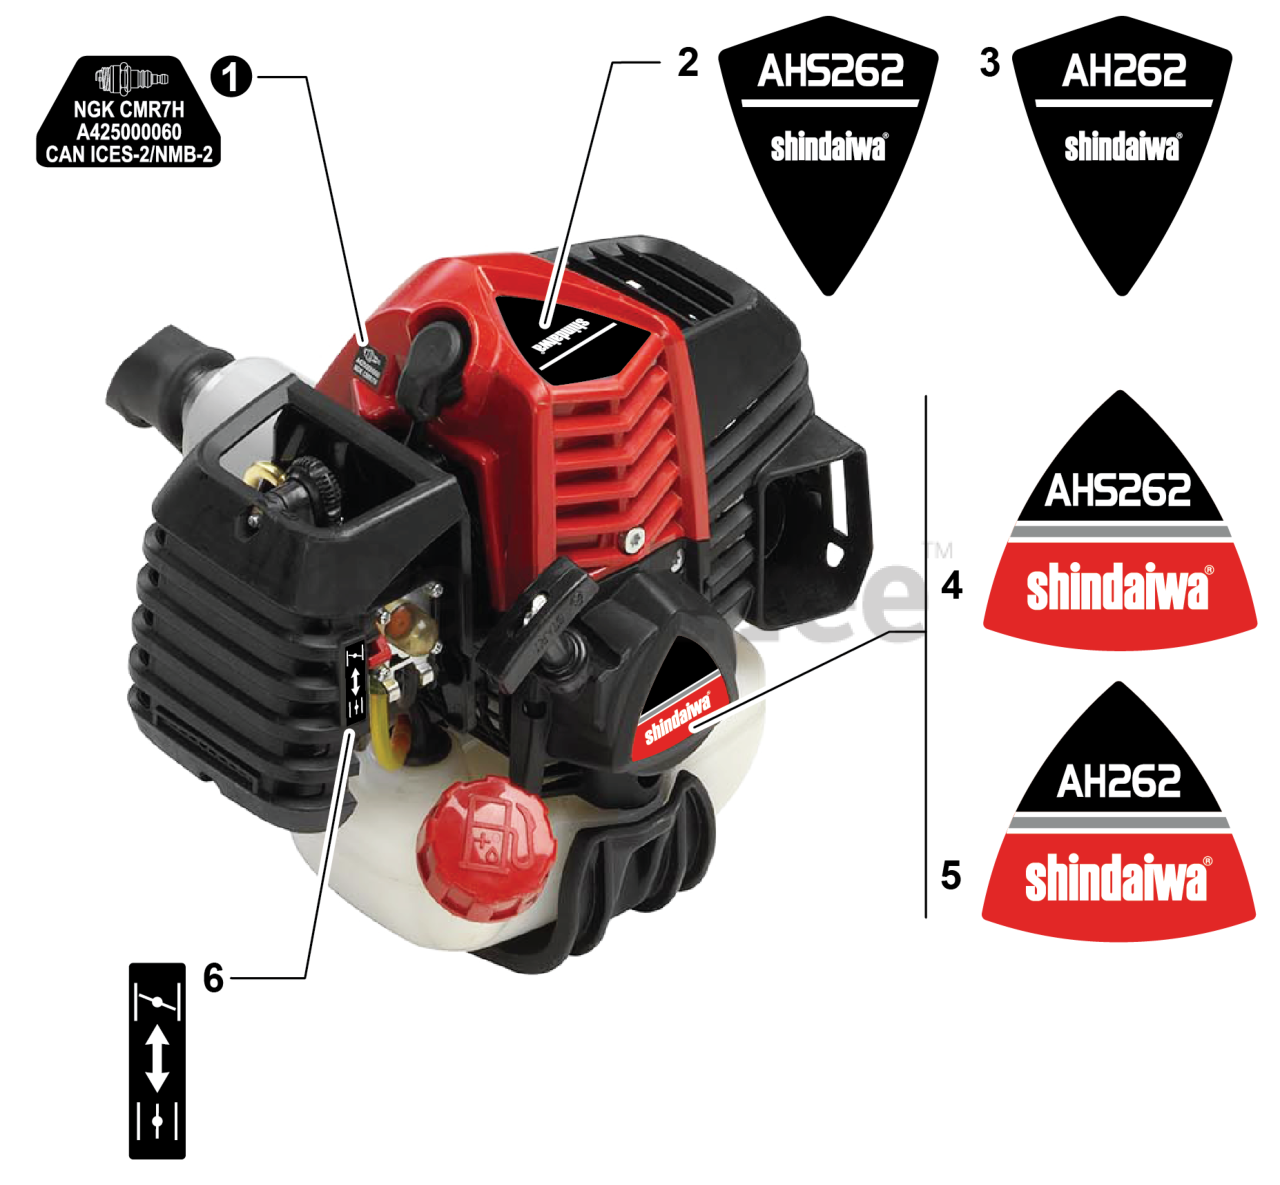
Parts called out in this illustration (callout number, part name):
1	LABEL - SPARK PLUG - CMR7H
2	LABEL - MODEL AHS262
3	LABEL - MODEL AH262
4	LABEL - RECOIL STARTER - AHS262
5	LABEL - RECOIL STARTER - AH262
6	LABEL - CHOKE
